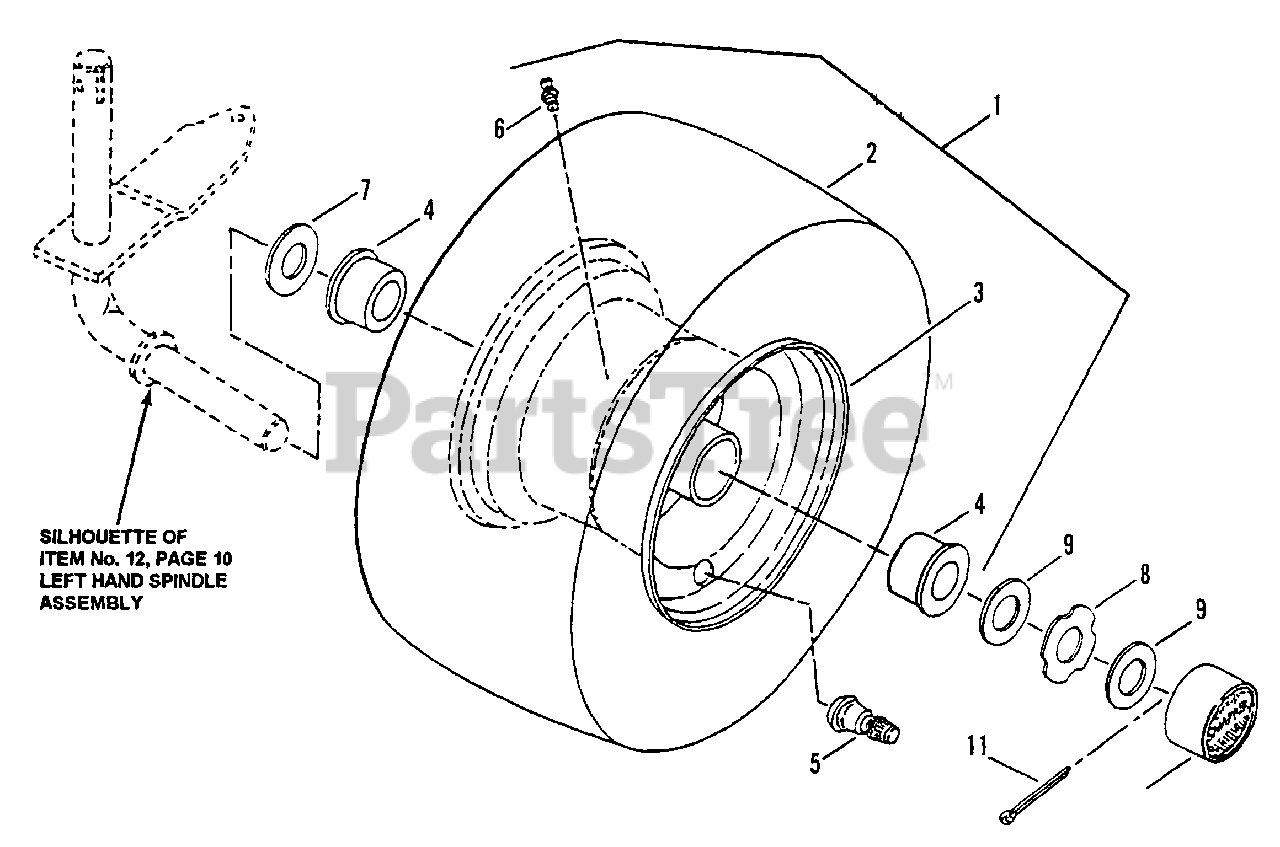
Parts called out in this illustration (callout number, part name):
1	ASSEMBLY, Front Tire & Rim
2	TIRE, 15 x 6.00
3	RIM, 5-1/2 x 4.00
3	RIM, 6.00 x 4.00 Grey
4	BEARING, Wheel
4	BEARING, Wheel (Heim)
5	VALVE, Air (Snap-in)
6	FITTING, Lube 1/4-28 Tapered Thread
7	WASHER, Flat, 5/32 x 25/32" I.D. x 1-1/2" O.D.
8	WASHER, Hub-Cap Retaining
9	WASHER, Flat, 1/16 x 49/64 I.D. x 1-5/16" O.D.
10	HUB-CAP
11	COTTER-PIN, 5/32 x 1"
